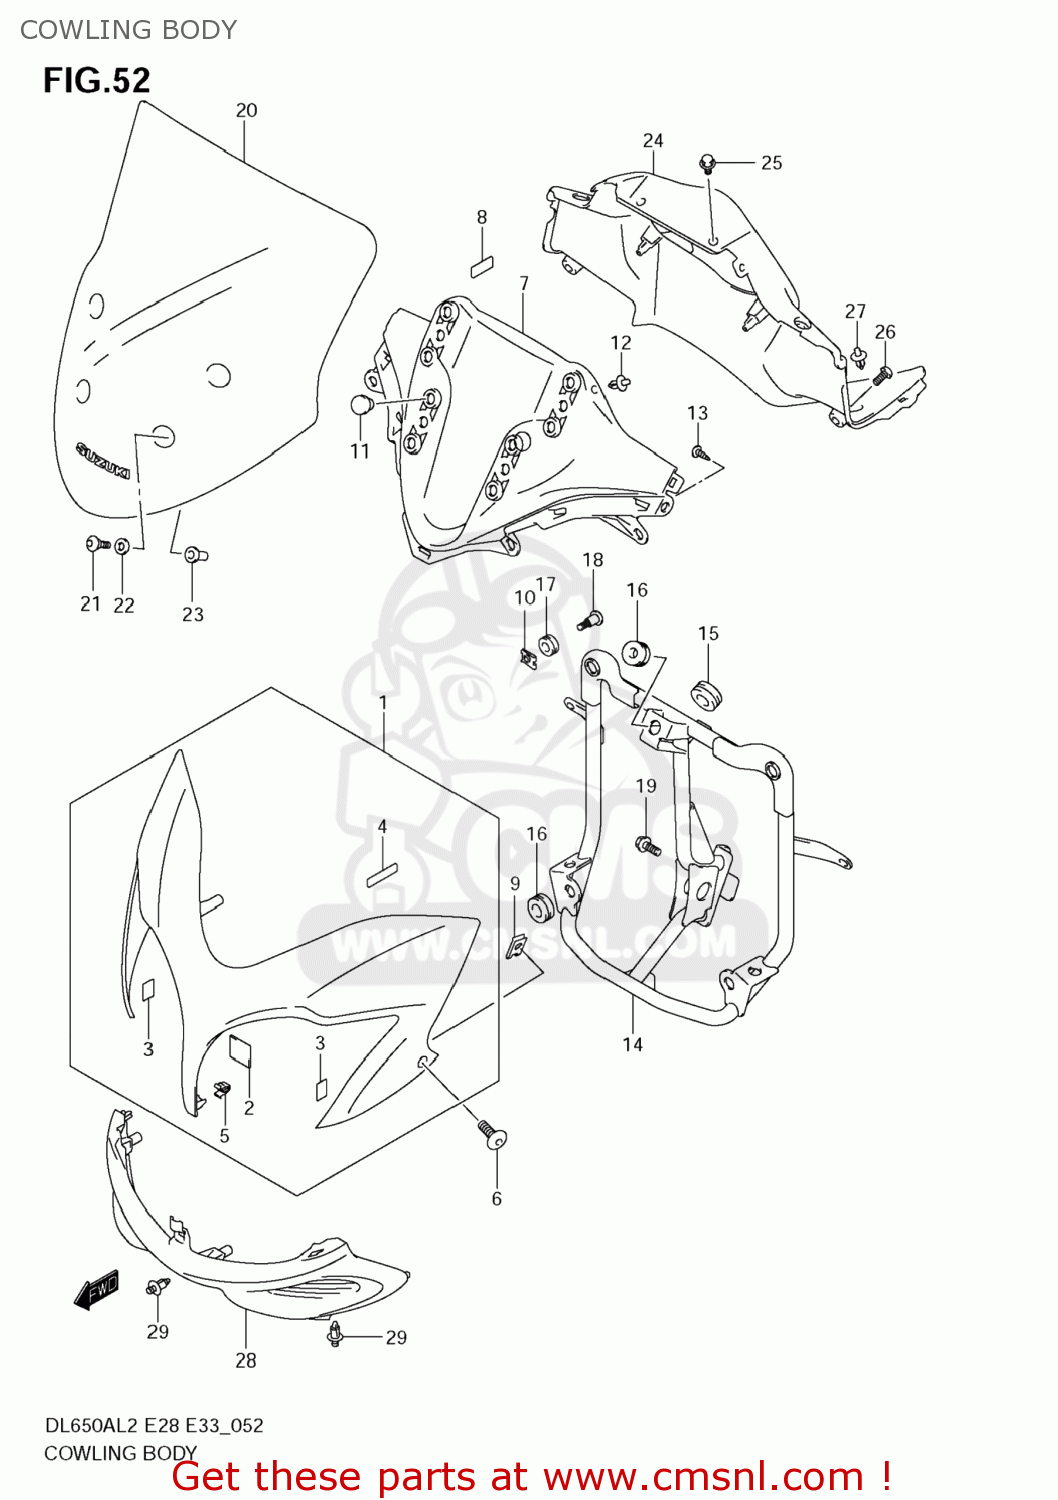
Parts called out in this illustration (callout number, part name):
1	COWLING,BODY(WHITE)
2	FASTENER
3	FASTENER,COWLING
4	TAPE(6X25X0.13)
5	CLIP
6	SCREW(5X13)
7	PANEL,FR
8	CUSHION
9	NUT
10	NUT
11	CAP(OD:15)
12	CLIP
13	SCREW
14	BRACE COMP,COW
15	CUSHION
16	CUSHION
17	CUSHION
18	SCREW(6X20)
19	BOLT
20	WINDSCREEN
21	SCREW(5X18)
22	WASHER(5.5X14X1.2)
23	NUT
24	PANEL,METER
25	BOLT(5X13)
26	SCREW(6X16)
27	CLIP
28	COVER,COWLING INNER
29	CLIP
